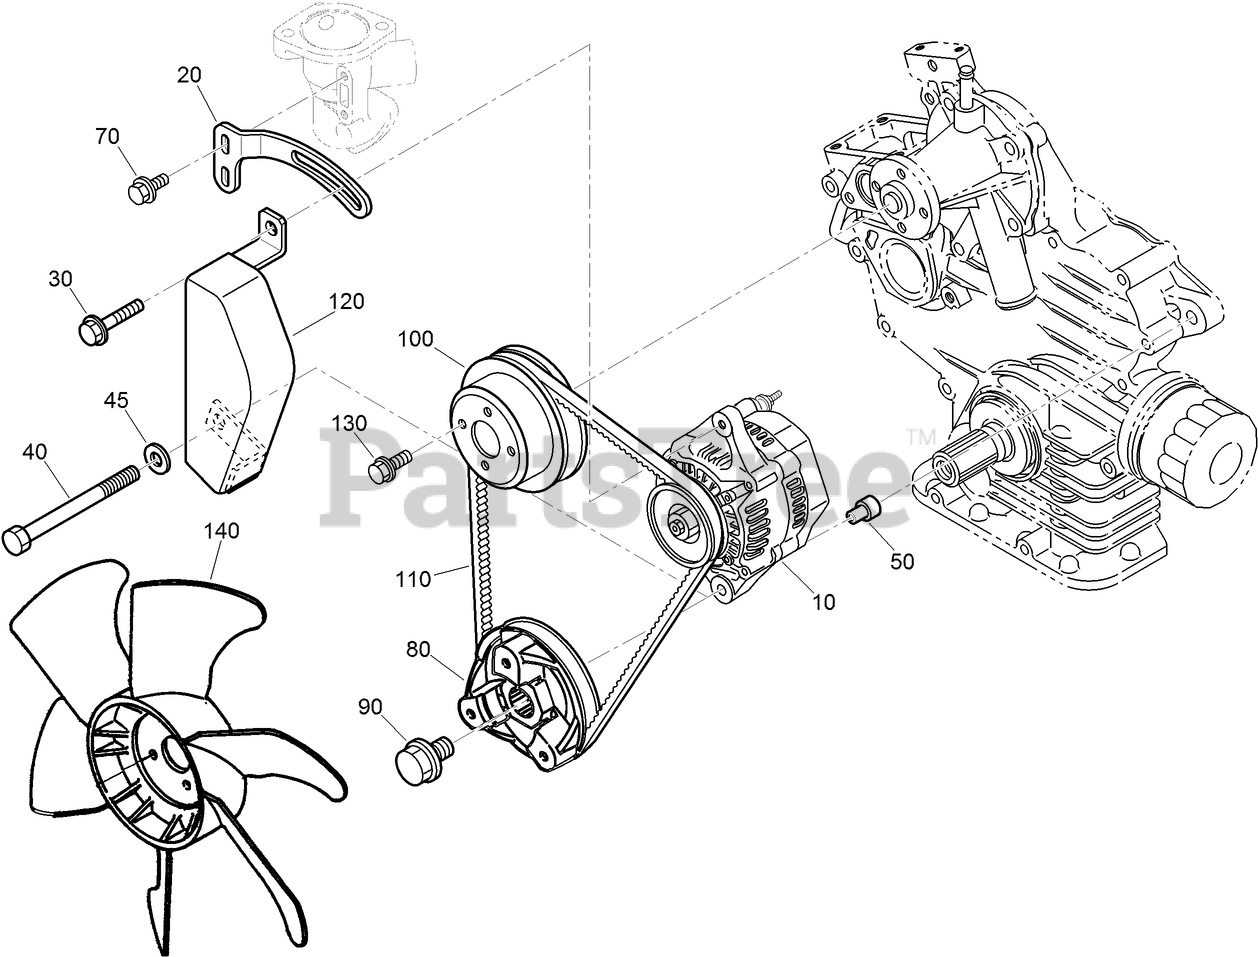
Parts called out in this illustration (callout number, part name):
20	STAY-ALTERNATOR
30	BOLT-SEMS
45	WASHER-PLAIN
50	COLLAR
80	PULLEY-DRIVE, FAN
100	PULLEY-FAN
130	BOLT-FLANGE
